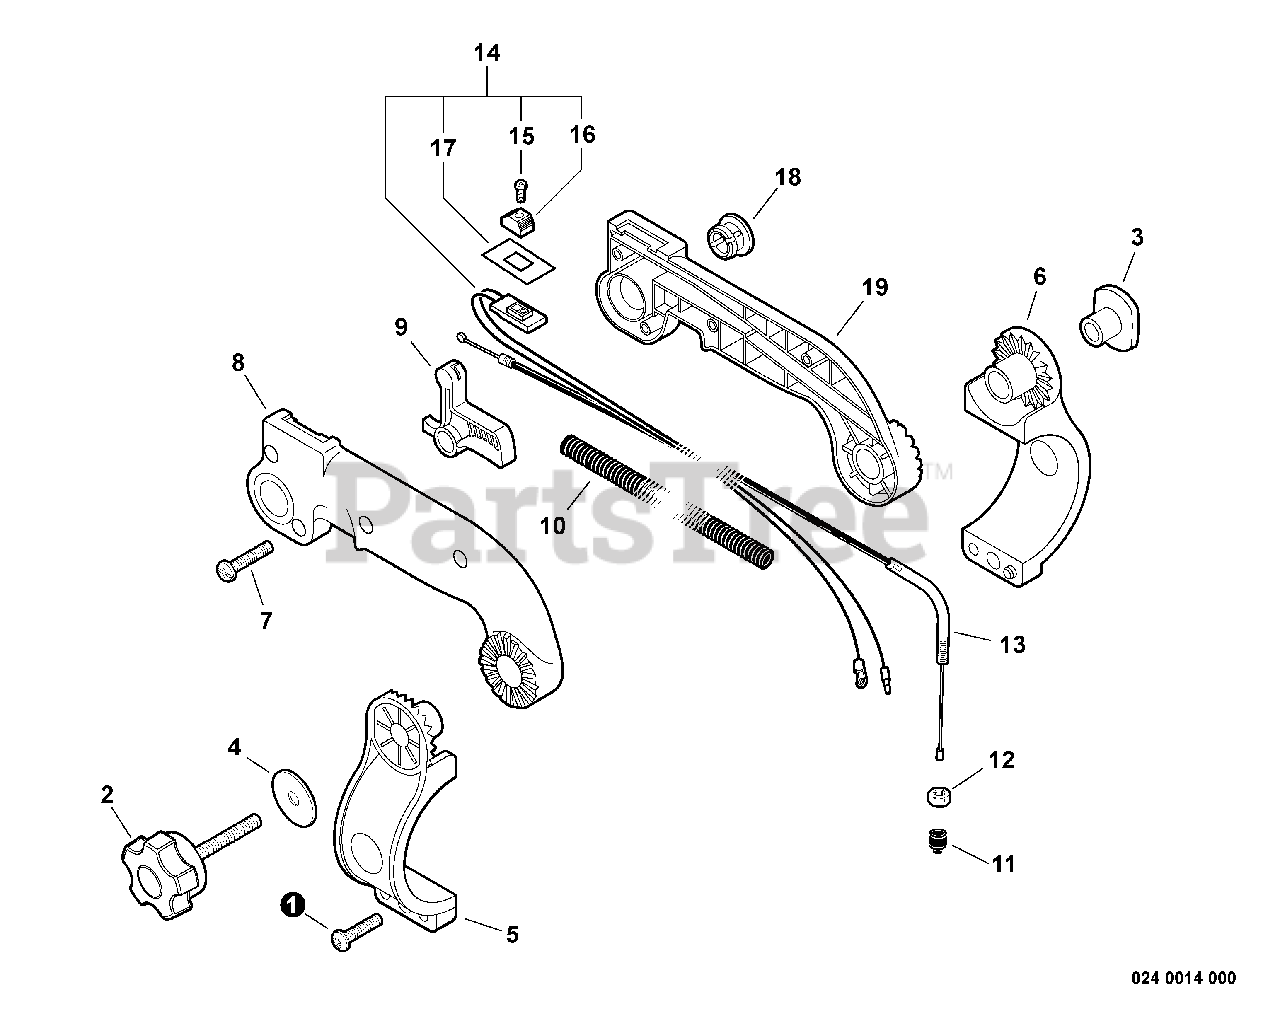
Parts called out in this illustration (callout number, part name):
1	SCREW, TAPPING 5×20
2	KNOB, SCREW
5	BRACKET, HANDLE - LEFT
6	BRACKET, HANDLE - RIGHT
7	SCREW 4×22
8	HANDLE, FRONT - LEFT
9	TRIGGER, THROTTLE
10	TUBE, FLEXIBLE 7×790
11	CAP, DUST
12	NUT, HEX M6
13	CABLE, THROTTLE
14	SWITCH, ON-OFF
15	SCREW 3×10
16	KNOB, SWITCH - ORANGE
17	LABEL, SWITCH
19	CONTROL HANDLE - RIGHT
